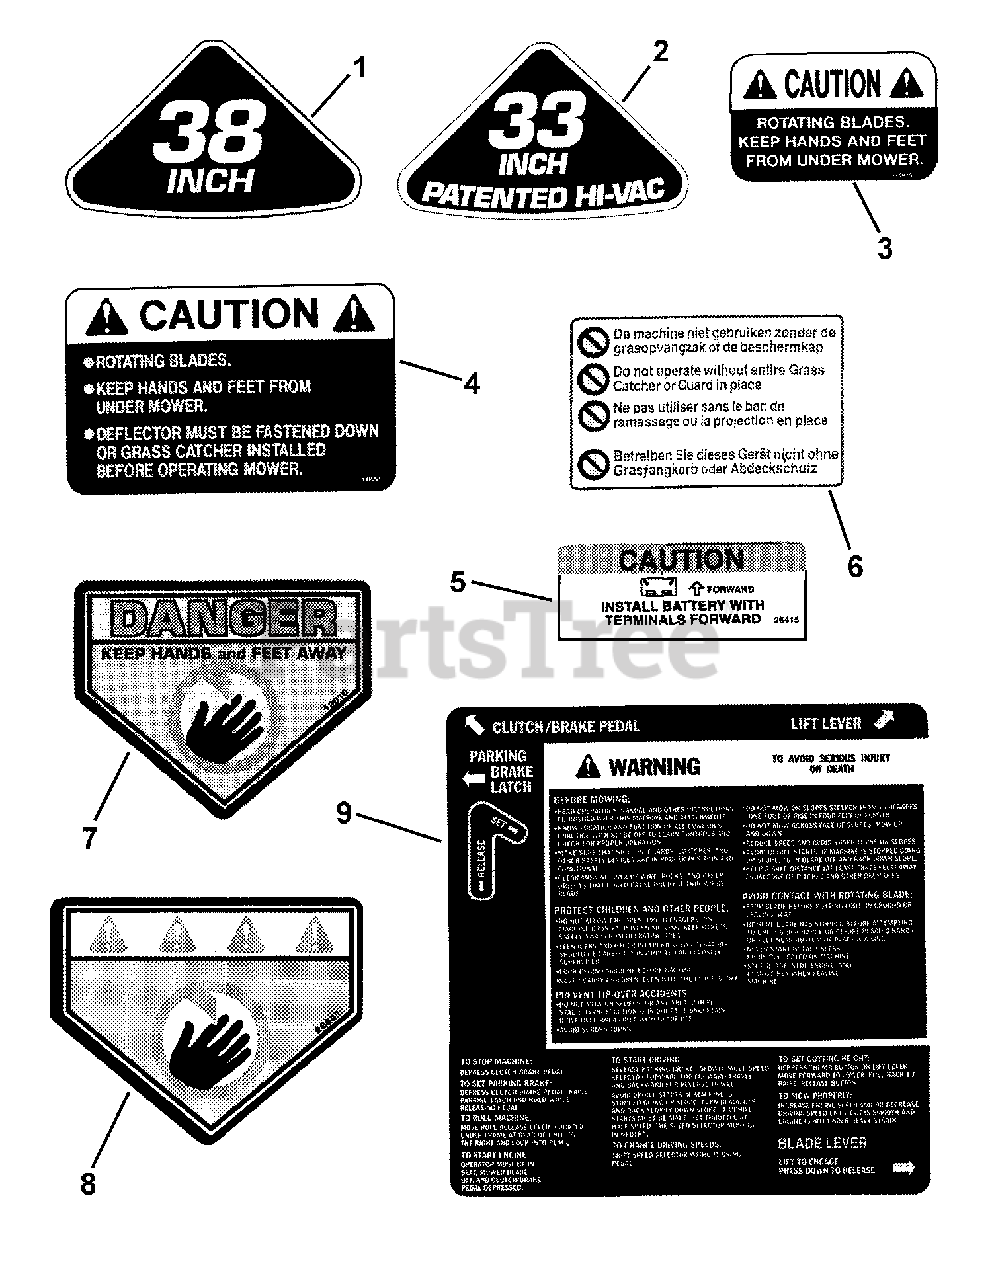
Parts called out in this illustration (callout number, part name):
1	DECAL, 38 Inch
2	DECAL, 33 Inch Hi-Vac
3	DECAL, Caution, Rotating Blades
4	DECAL, Caution, Rotating Blades
5	DECAL, Caution-Battery Installation Fender
6	DECAL, Deck/Chute International Warning
7	DECAL, Danger, Cut Finger
